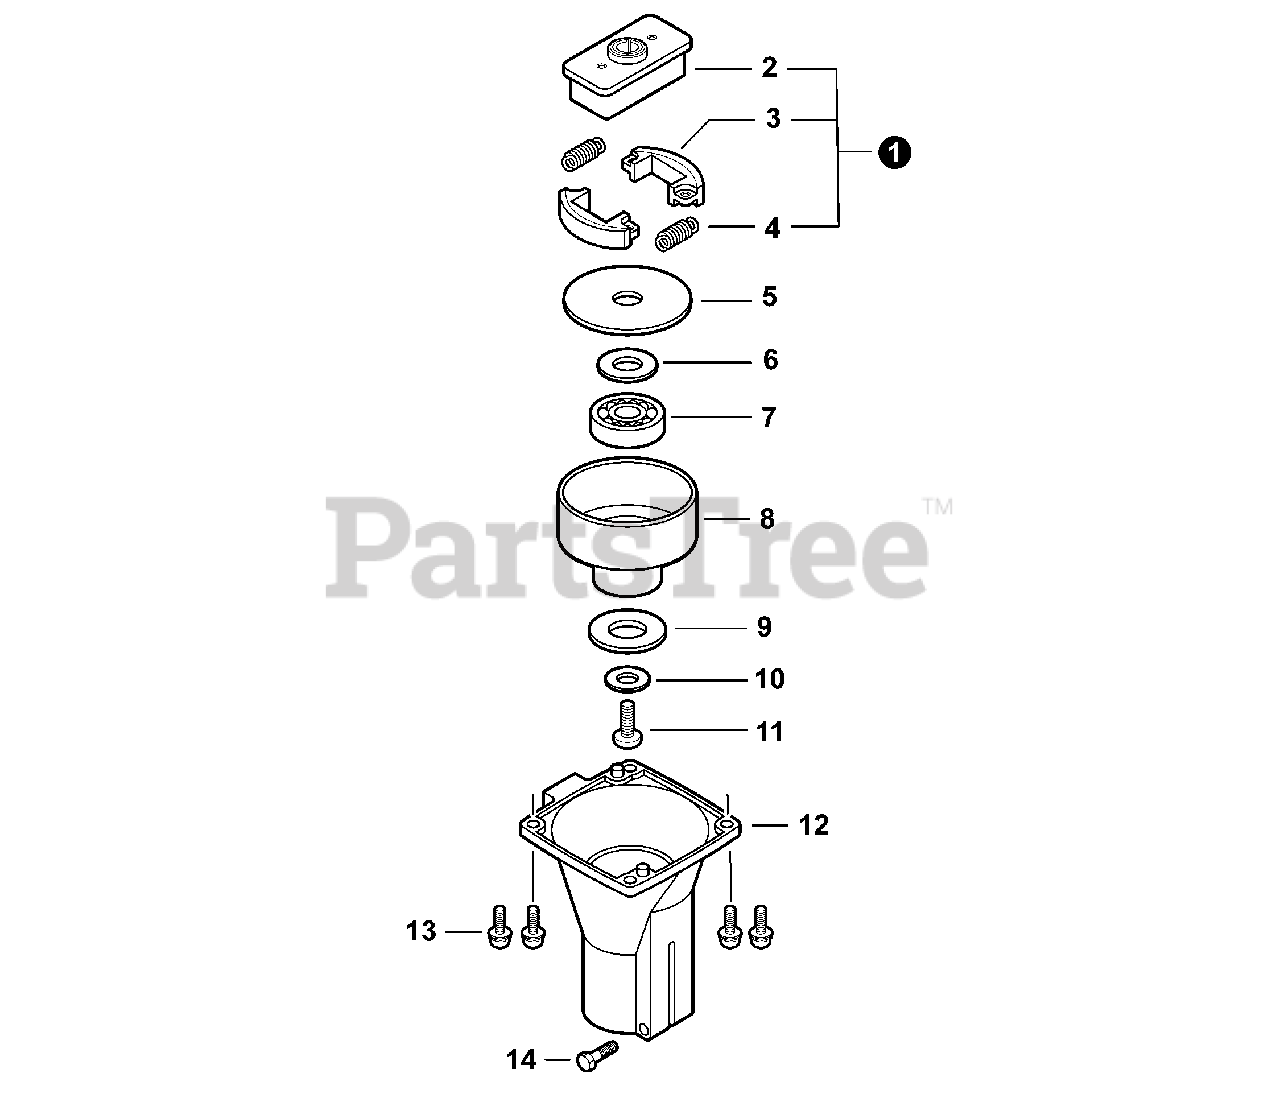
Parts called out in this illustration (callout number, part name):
1	CLUTCH ASSY
2	HUB, CLUTCH
3	SHOE, CLUTCH
4	SPRING, CLUTCH
5	PLATE, CLUTCH
6	WASHER 10.5×18×1.6
7	BEARING, BALL 6000-2RLB
8	DRUM, CLUTCH
10	WASHER, CLUTCH
11	SCREW 6×12
12	CASE, CLUTCH
13	SCREW 4×18
14	BOLT 5
